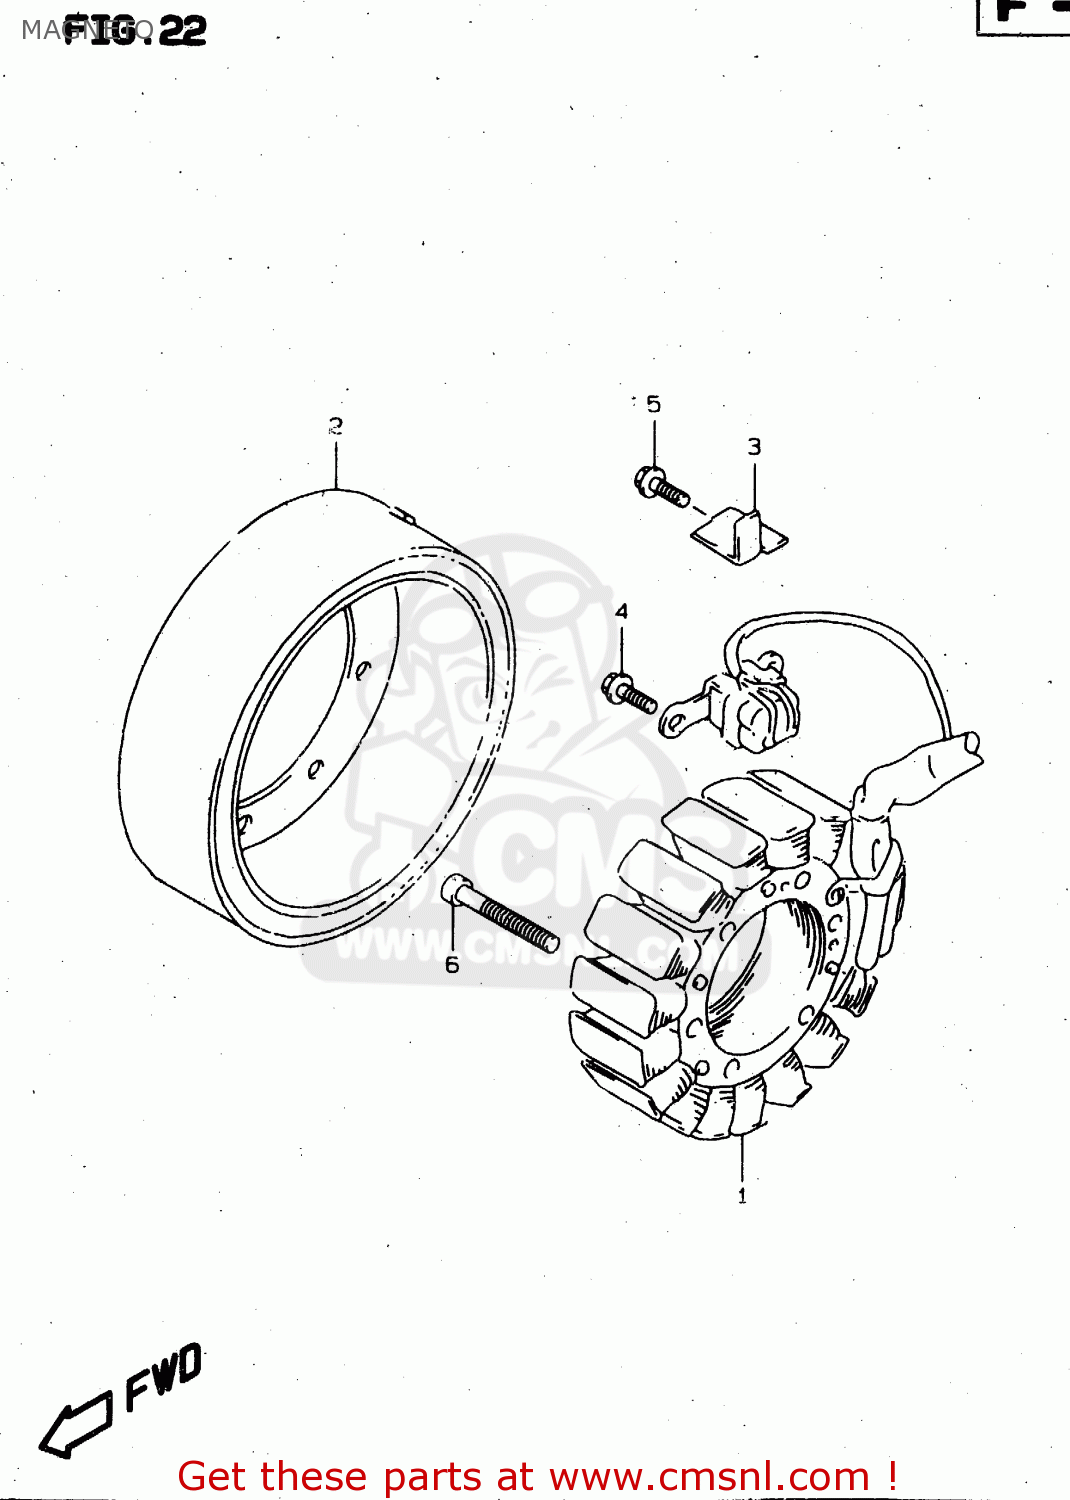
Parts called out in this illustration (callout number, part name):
1	STARTER ASSY
2	ROTOR ASSY
3	CLAMP,MAGNETO LEAD NO.1
4	BOLT
5	BOLT
6	BOLT
